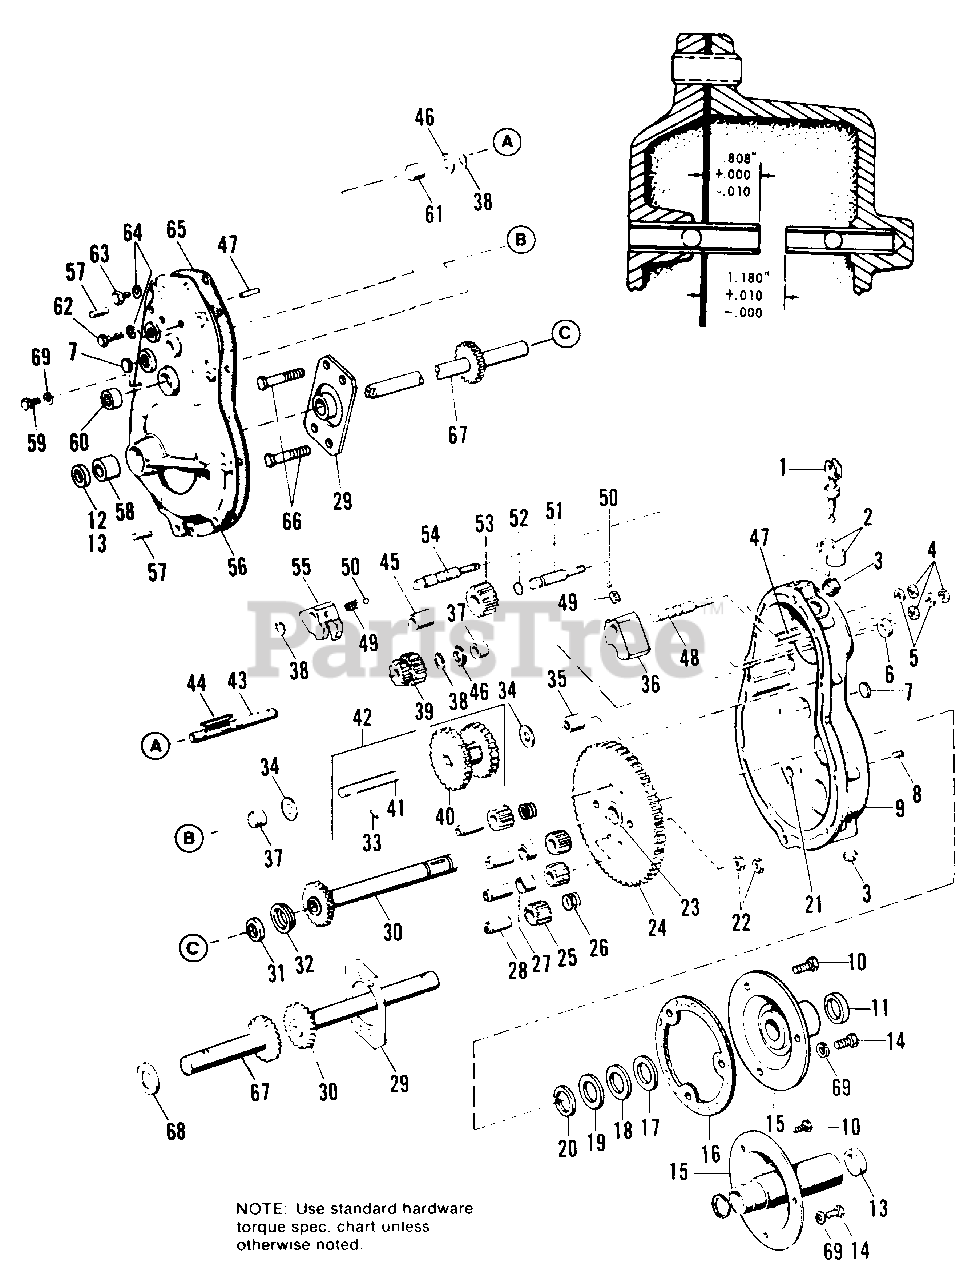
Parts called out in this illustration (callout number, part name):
1	ROD ASSY., Shift
2	BUSHING, Half
4	NUT, Hex, Full, 7/16-14
5	WASHER, Plain, 3/8
7	PLUG, Extension (990560 Only)
8	SETSCREW, 3/8-16 x 3/8
9	CASE ASSY., Gear (Includes Ref. Nos. 1, 2, 35, 37, 47 & 57)
9	CASE ASSY., Gear (990372 Only) (Includes Ref. Nos. 1, 2, 35, 37, 47, & 57)
10	SCREW, Special
11	SEAL, Oil (990560 Only)
12	SEAL, Oil (990560 Only)
13	SEAL, Oil (990372 & 990430 Only)
14	CAPSCREW, Hex Hd., 3/8-16 x 7/8
15	SUPPORT ASSY., Plate
15	SUPPORT ASSY., Plate (990372 & 990430 Only)
16	GASKET (990560 Only)
17	WASHER (990560 Only)
18	WASHER (990560 Only)
19	WASHER (990560 Only)
20	RING, Retaining (990560 Only)
21	PLUG, Pipe, 3/8
22	LOCKNUT, Hex, 3/8-16
23	BUSHING (990560 Only)
24	GEAR ASSY., Drive
24	GEAR ASSY., Drive (990372 & 990430 Only)
25	PINION, Diff.
27	SPACER, Diff.
28	SPACER, Pinion, Diff.
29	PLATE ASSY., Diff.
29	PLATE, Diff. (990372 & 990430 Only)
30	SHAFT ASSY., Axle, R.H.
30	SHAFT ASSY., R.H. (990372 & 990430 Only)
31	SEAL, Oil (990560 Only)
32	CUP, Thrust (990560 Only)
33	PIN, Dowel
35	BEARING, Roller
36	FORK, Shift, I & II
37	BEARING, Roller
